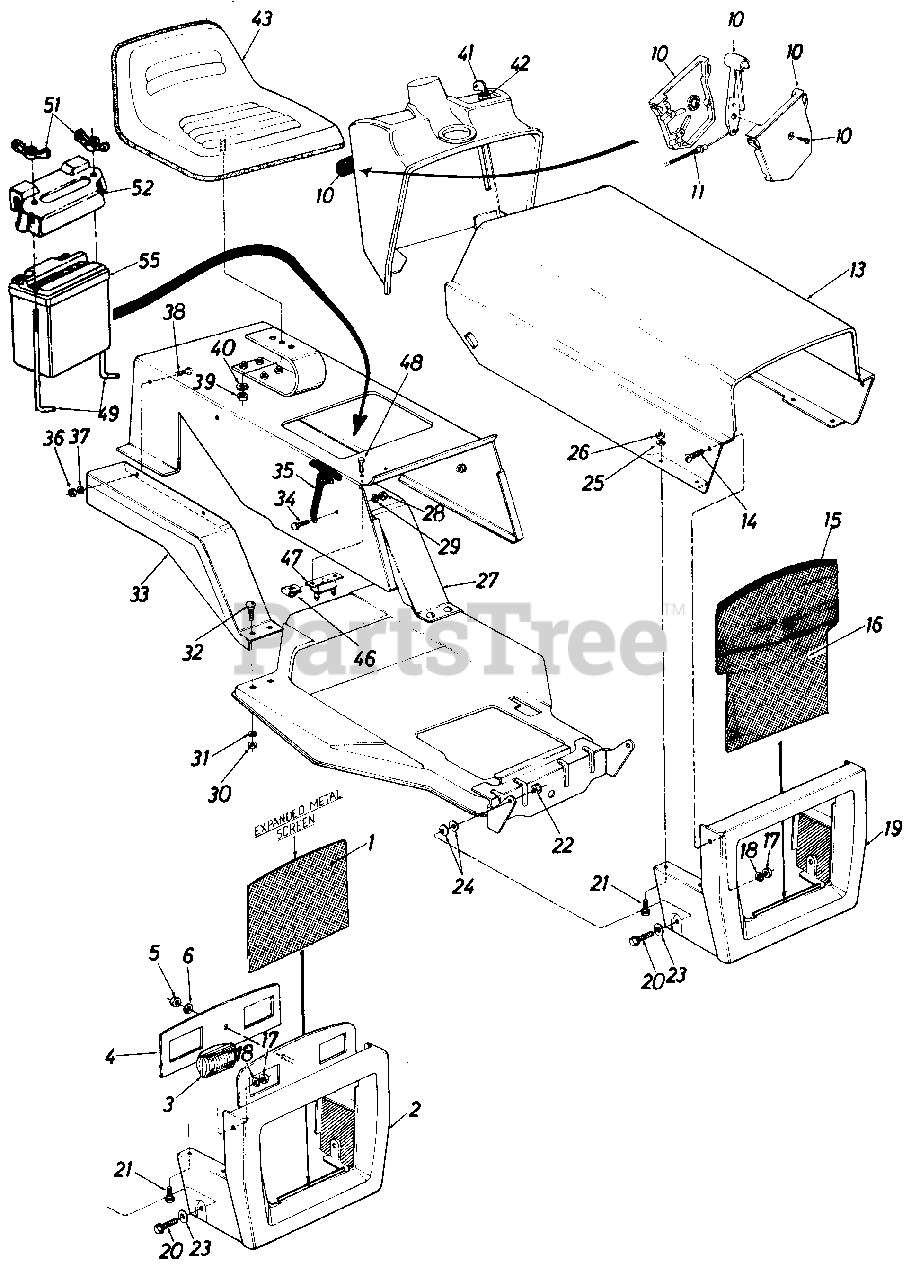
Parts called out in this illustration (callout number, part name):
1	Screen-Grille
2	Grille Ass'y.
3	Head Light
4	Head Light Retainer
5	Hex Nut #10-24 Thd.
6	L-Wash. #10 I.D.
10	Throttle Control Box Ass'y.
11	Throttle Control Wire
13	Hood-Front
14	Truss Hd. Mach. Scr. 1/4-20 x.50" Lg.
15	Extruded"U"-Channel 22.50" Lg.
16	Screen-Grille
17	Hex Nut 1/4-20 Thd.
18	L-Wash. 1/4" Scr.
19	Grille Ass'y.
20	Hex Scr. 3/8-16 x 1.00" Lg.
21	Hex Sems Scr. 1/4-20 x .75" Lg.
22	Hex Cent. L-Nut 3/8-16 Thd.
23	Fl-Wash. .385 I.D. x .620 O.D. x .063
24	Bell-Wash. .400 I.D. x .88 O.D.
25	L-Wash. 1/4" Scr.
26	Hex Nut 1/4-20 Thd.
27	Fender Ass'y. L.H.
28	Hex Nut 1/4-20 Thd.
29	L-Wash. 1/4" Scr.
30	Hex Nut 1/4-20 Thd.
31	L-Wash. 1/4" Scr.
32	Carriage Bolt 1/4-20 x .62" Lg.
33	Fender Ass'y. R.H.
34	Hex Scr. 1/4-20 x .62" Lg.
35	Hood Lock Ass'y.
36	Hex Nut 10-24 Thd.
37	Wash. #10 Scr. xt.
38	Truss Hd. Mach. Scr. 10-24 x.62" Lg.
39	Hex Nut 1/2-13 Thd.
40	L-Wash. 1/2" Scr.
41	Ignition Key
42	Ignition Switch
43	Seat Ass'y. w/Safety Switch
46	Speed Nut 10-24
47	Circuit Breaker
48	Truss Hd. Mach. Scr. #10-14 x.62" Lg.
49	Hold-Down Rod
51	Wing Nut 1/4-20 Thd.
52	Battery Cover
55	12V Battery
